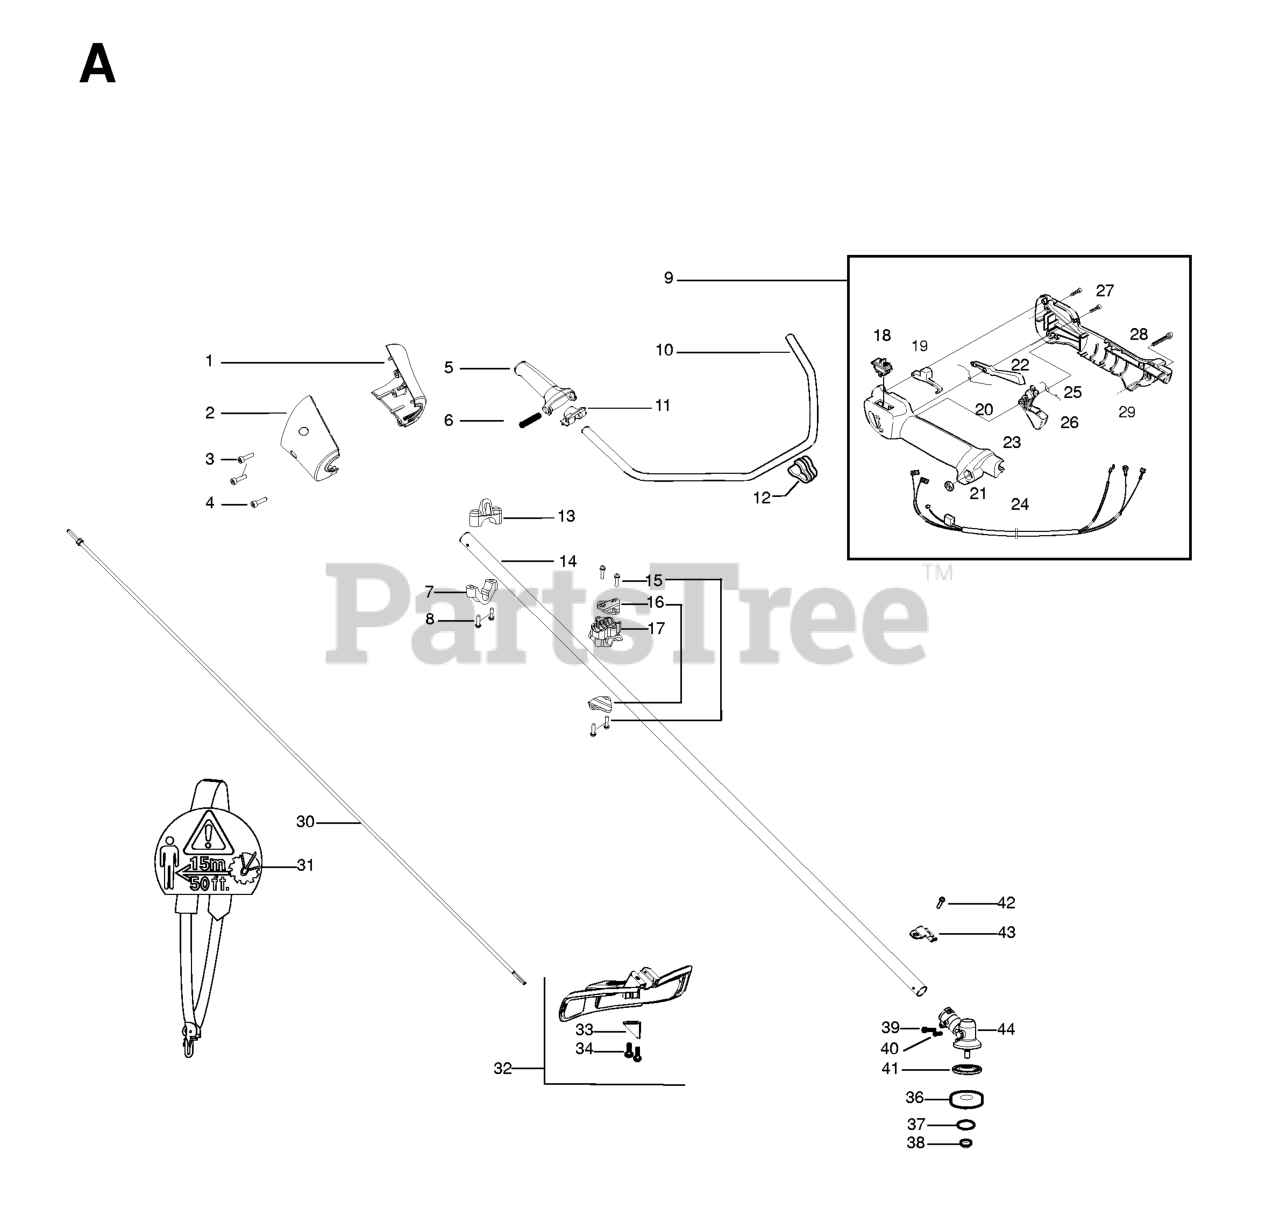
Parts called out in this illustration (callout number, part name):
1	NOSE CONE BH LEFT
2	NOSE CONE BH RIGHT
4	SCREW M4 X 1.75 PT 16MM
7	CLAMP HARNESS LOWER
9	ASSY THROTTLE HOUSING
13	CLAMP HARNESS UPPER
14	KIT DRIVESHAFT SST
16	CLAMP BRACKET
18	KIT SWITCH
19	LOCKOUT STARTER THROTTLE
22	THROTTLE LOCK
24	THROTTLE CABLE
26	THROTTLE TRIGGER
28	SCREW
30	FLEXSHAFT 57"
31	Harness - Diagonal with sign
32	KIT COBI SHIELD
33	Limiter - Line
36	SUPPORTING CUP
37	SUPPORT FLANGE
38	GEARHEAD NUT - BRUSHCUTTER
39	SCREW - CARB. ADAPTOR
41	ASSY DUST CUP
42	SCREW 1/4-20 X 7/8 (TAP
43	BRACKET SHIELD STRAIGHT SHAFT
44	ASSY GEARBOX
502114602	COMBI WRENCH
530031159	HEX WRENCH 5/32
537312901	BLADE GUARD TRANSPORT
545047543	MANUAL OPERATORS
545056101	DECAL SHAFT WARNING EU
